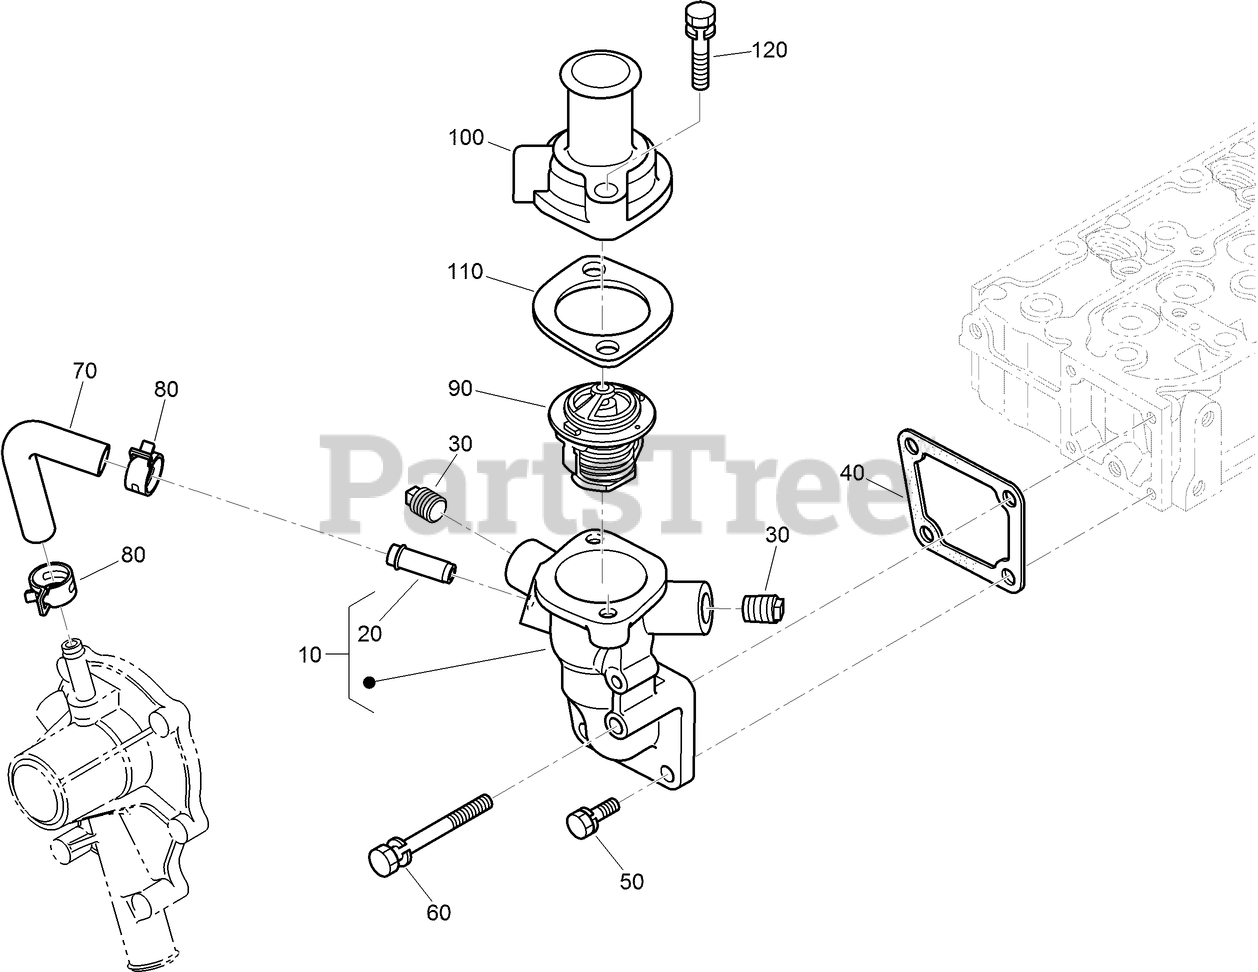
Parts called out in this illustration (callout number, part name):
10	WATER FLANGE ASM
20	PIPE-RETURN, WATER
40	GASKET-FLANGE, WATER
70	PIPE-RETURN, WATER
80	CLAMP-HOSE
90	THERMOSTAT ASM
100	COVER-THERMOSTAT
110	GASKET-THERMOSTAT
